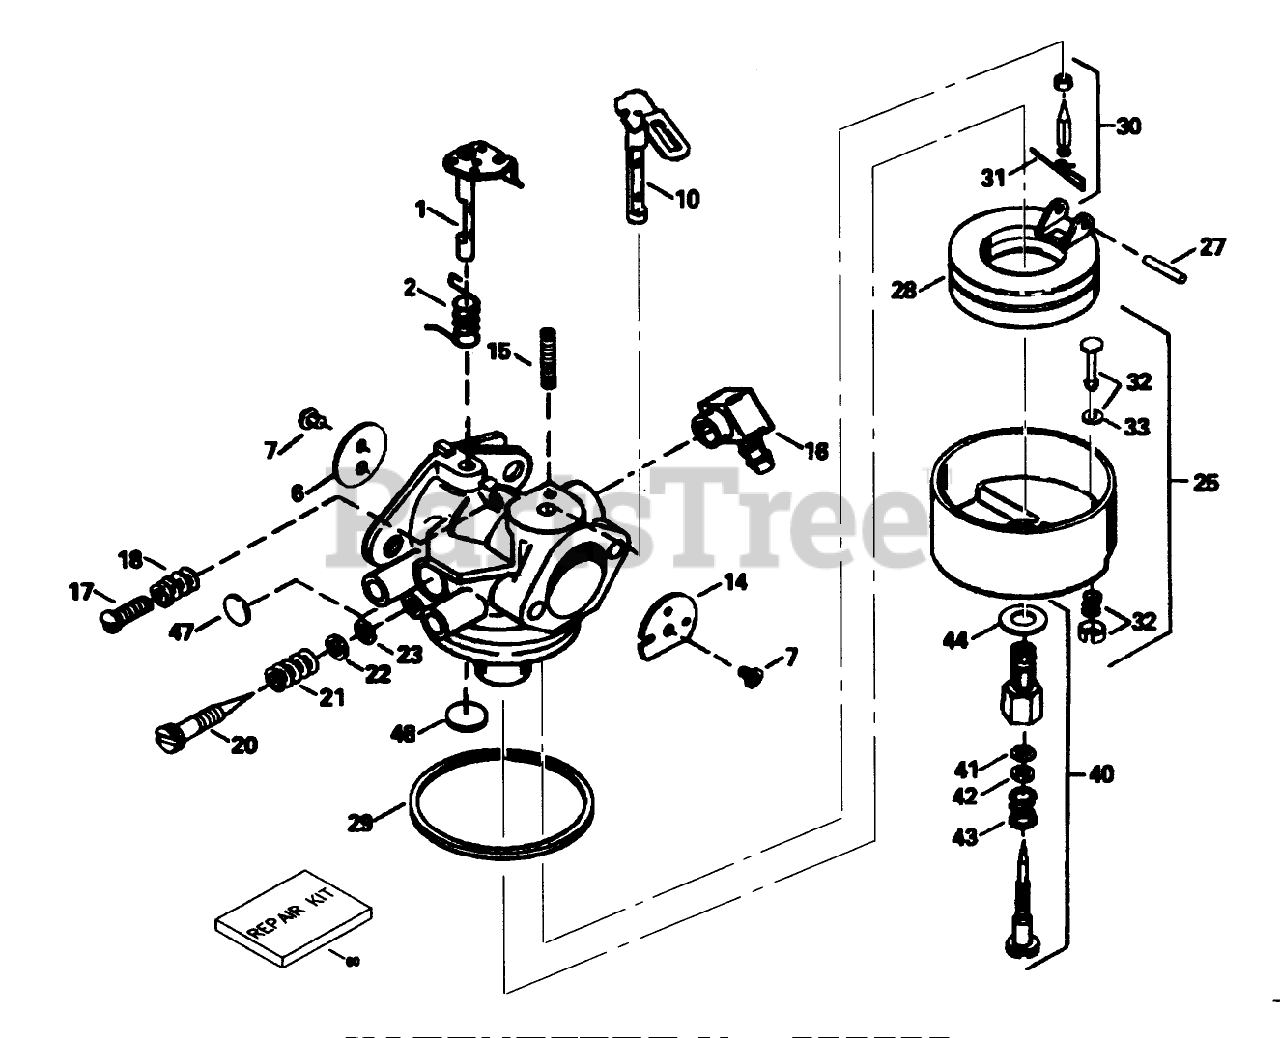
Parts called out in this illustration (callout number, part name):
1	Throttle-Shaft Lever Asm
2	Spring-Return, Throttle
6	Shutter-Throttle
7	Screw-Shutter
10	Choke Shaft Lever ASM
14	Choke Shutter
15	Spring-Positioning, Choke
16	Fitting-Fuel
17	Screw-Throttle Crack Screw / Idle Speed
18	Spring-Tension
20	Screw-Idle Mix
21	Spring-Tension
22	Washer
23	ORing
25	Float-Asm (Incl. Ref. # 32 33)
27	Shaft-Float
28	Float
29	O Ring-Bowl, Float
30	Inlet Needle, Seat Clip Assy. (Incl. No. 13)
31	Clip-Spring
32	Bowl Drain ASM
33	Gasket-Plunger, Drain
40	Adjustment Screw Assy.,Main (Incl. Ref. #5A,21,23 30)
41	ORing
42	Washer
43	Spring
44	Washer-Bowl Nut
47	Plug-Welch, Idle Mixture Well
48	Plug-Welch, Atmospheric Vent
60	Kit-Repair
